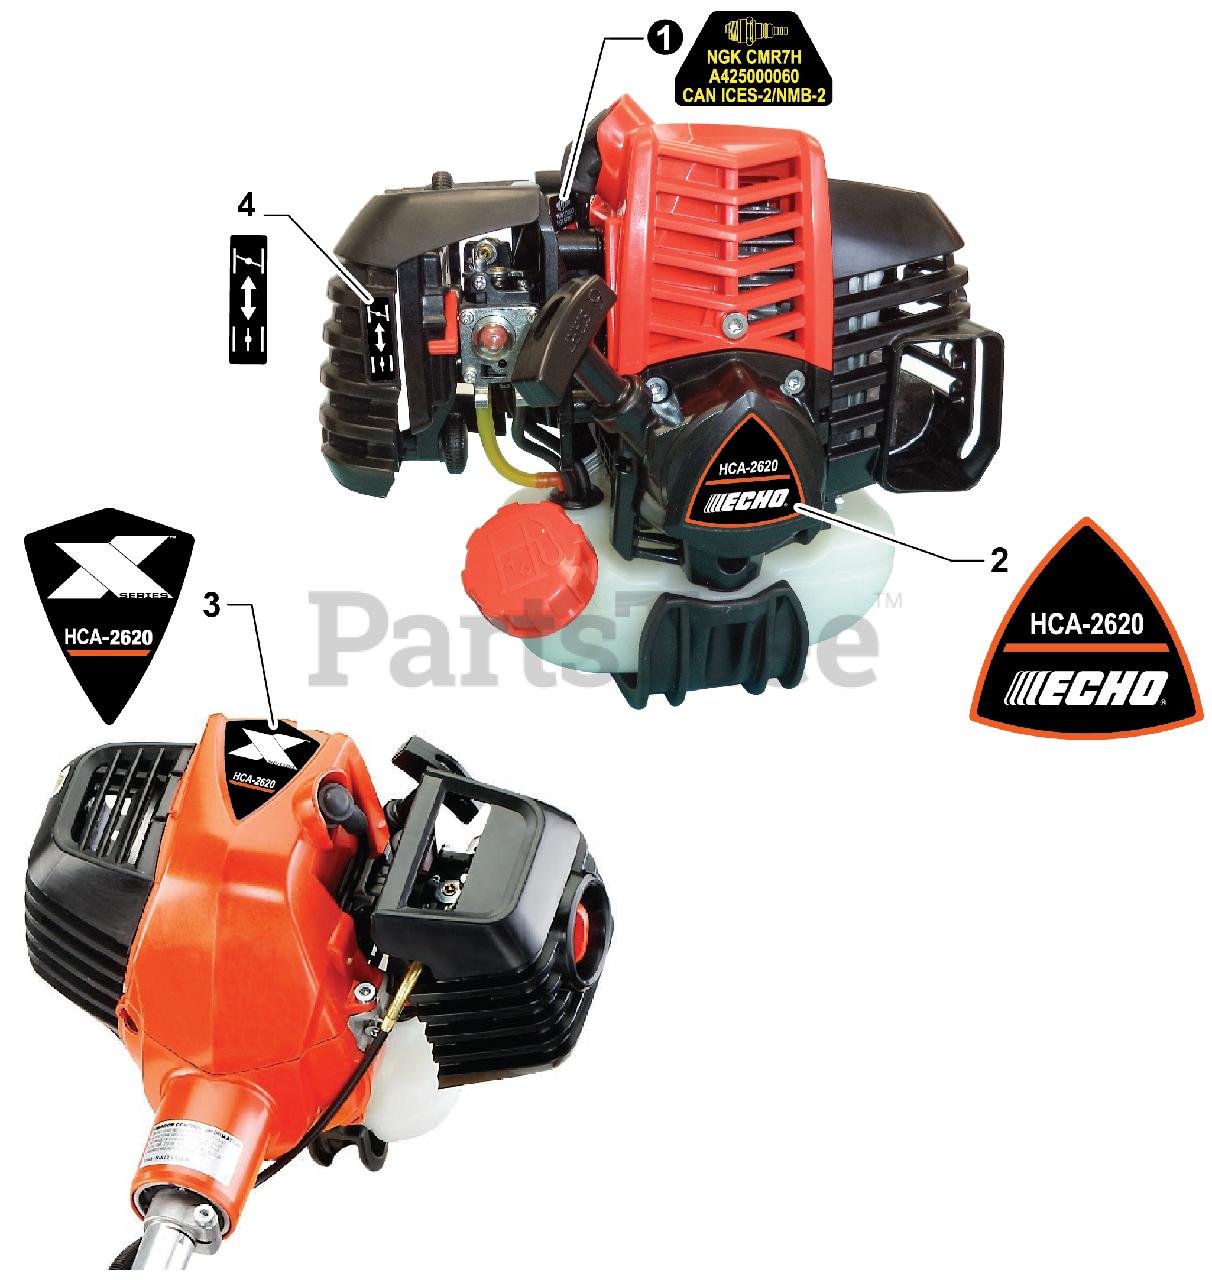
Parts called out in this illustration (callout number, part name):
1	LABEL, SPARK PLUG - CMR7H
2	LABEL, RECOIL STARTER - HCA-2620
3	LABEL - MODEL HCA-2620
4	LABEL, CHOKE
